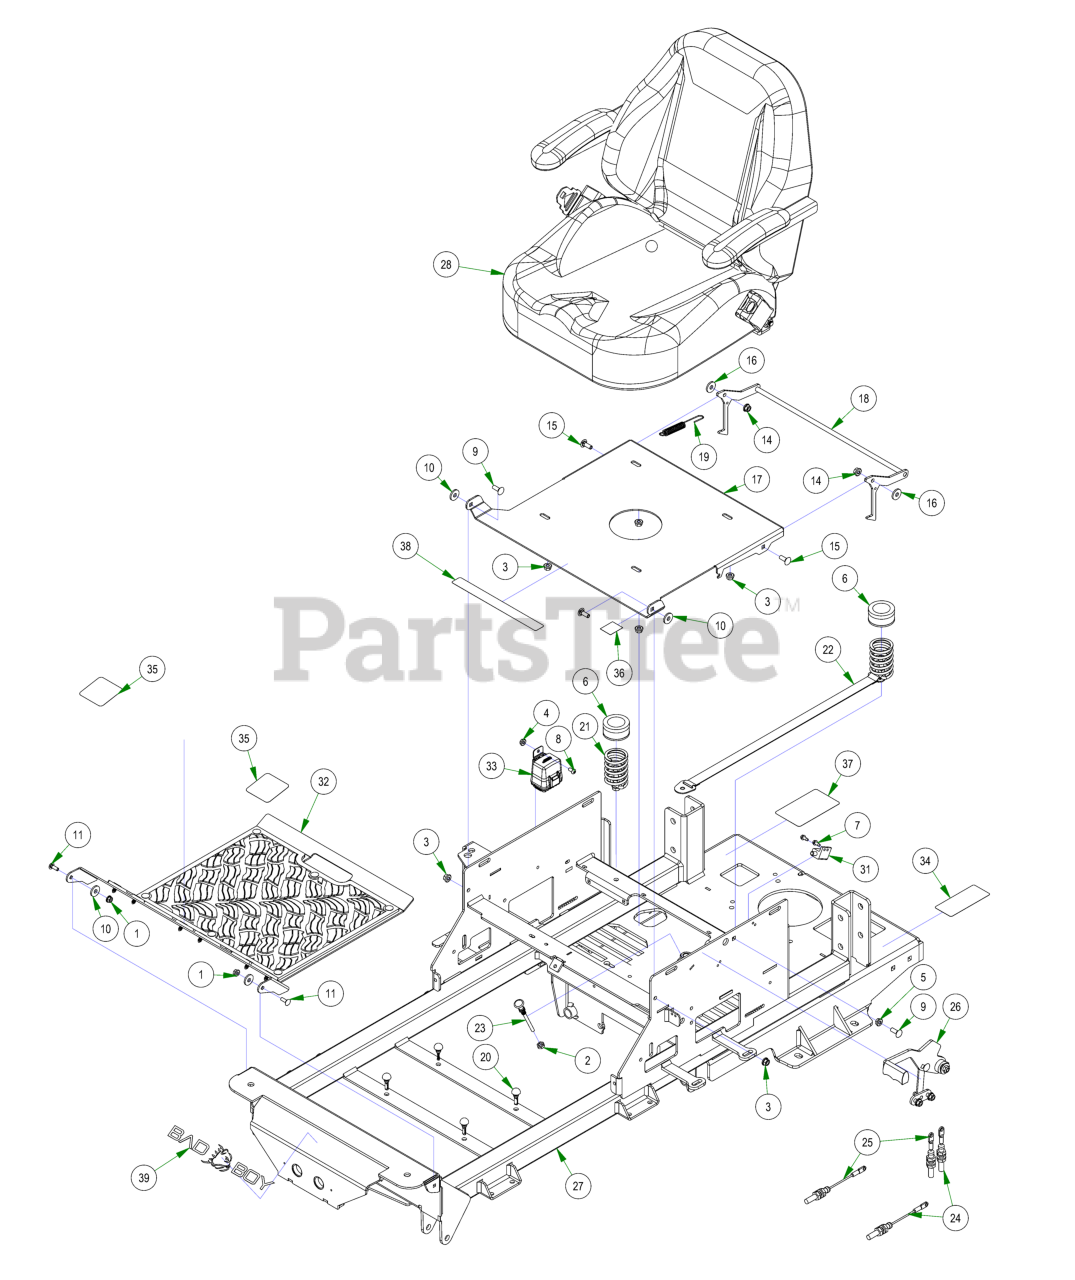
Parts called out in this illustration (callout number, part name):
1	1/4-20 NYL INSERT FLANGE LOCKNUT ZINC
2	3/8-24 HEX NUT ZINC YELLOW
3	5/16-18 NYLON INSERT FLANGE LOCKNUT ZINC
4	1/4-20 HEX SERRATED FLANGE NUT HARD/ZINC
5	5/16-18 HEX SERRATED FLANGE NUT HARD/ZINC
6	Seat Spring Cap Cover
7	12-24 X 1/2 HEX WASHER UNLSOT F TCS ZINC
8	1/4-20 X 1/2 BUTTON SOCKET CAP SCREW 18-8 STAINLESS STEEL
9	5/16-18 X 7/8 CARRIAGE BOLT ZINC
10	.360 ID X .983 OD X .120 THICK FLAT WASHER NYLON
11	1/4-20 X 3/4 CARRIAGE BOLT (GR.5) ZINC
12	2022 Maverick Rear Cover Assembly
13	MAVERICK/COMPACT OUTLAW SEAT PLATE ASSEMBLY
14	5/16-18 NYLON INSERT FLANGE LOCKNUT ZINC
15	5/16-18 X 7/8 CARRIAGE BOLT ZINC
16	.360 ID X .983 OD X .120 THICK FLAT WASHER NYLON
17	Seat Plate 2016
18	Seat Latch Rod Assembly
19	Brake Spring
20	2023 Floor Board Rubber Bumper
21	Seat Spring Assembly
22	2022 Mav/HD seat spring assembly with strap
24	2021 Load Balanced Brake Cable 1
25	2021 Load Balanced Brake Cable 2
26	2021 Load Balanced Brake Handle Assembly
27	2023 Maverick Frame - Painted
28	2024 Maverick Digital Seat
29	Seat Slide 6.5" Latch Slid w/3 holes 2024 Maverick
30	Seat Slide (Slave) w/3 holes 2024 Maverick
31	Safety Switch
32	2021 Maverick Floorboard Assembly
33	2024 Wiring Harness with Clips
34	2024 EPA Build Date Punch Decal
35	2018 Maverick/2021 ZT Anti-Skid Steering Control Decals
36	2018 MZ/Magnum/ZT/MAV/Comp Out Brake Decal
37	Maverick Pump Belt Decal
38	Outlaw Warning Decal
39	Flying Bulldog Front Bumper Decal
